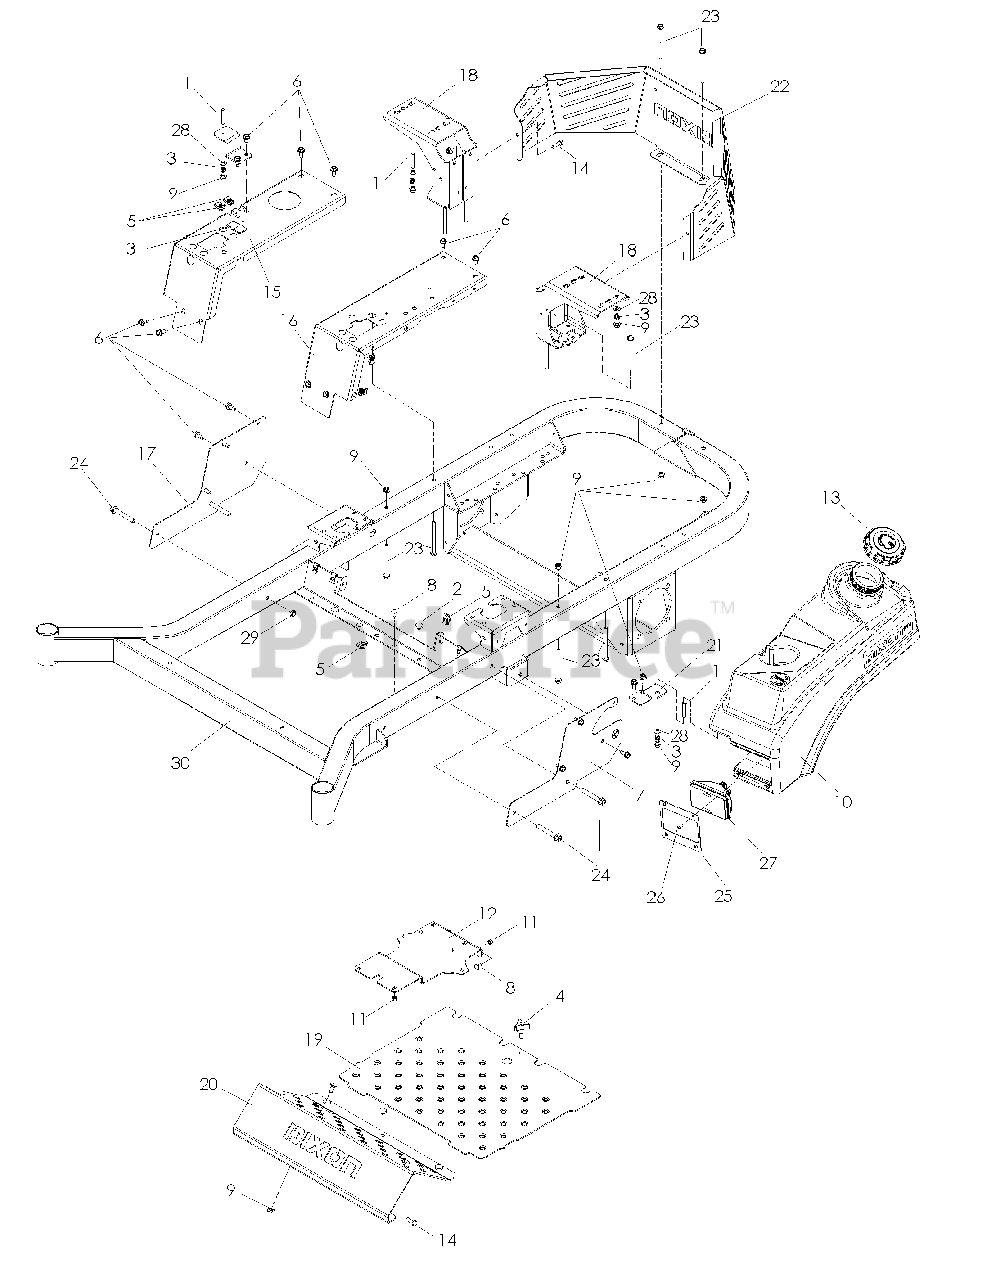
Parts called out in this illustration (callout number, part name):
1	STUD, 5/16C
2	GROMMET, BUMPER
4	KNOB W/STUD
5	U-CLIP 5/16-18 NUT RETAINER
6	BOLT 5/16-18 X 3/4
7	SIDE, LT, BL
8	RHSSNB, 1/4-20X5/8
9	5/16-18 NYLOC FLANGE NUT
10	TANK, FUEL, LT
11	NUT 1/4-20 NYLOC
12	BATTERY MOUNT
13	FUEL CAP ANTI-SPLASH
14	BOLT 5/16C X 3/4" CARRIAGE
15	PANEL, FILLER, RT, DK BLUE
16	PANEL, FILLER, LT - BLUE
17	SIDE, RT, BL
18	MOUNT, TANK, RR
19	FLOOR PAN W/DECALS
20	PLATE, FOOTREST, BL
21	SUPPORT, TANK, FT, BLK
22	GUARD, REAR, DIXON, BL
23	HHFS 5/16-18 X 3 3/4
24	HHFS 3/8-16 X 2 3/4
25	PLATE LIGHT
26	SCR #10-24 X 3/8 SKT HD BLK OX
28	FLAT WASHER 5/16 SAE
29	NUT HEX 3/8-16 NYLON, THIN
30	FRAME W/DECALS
30	FRAME W/DECALS, 72
31	PLUG DASH
